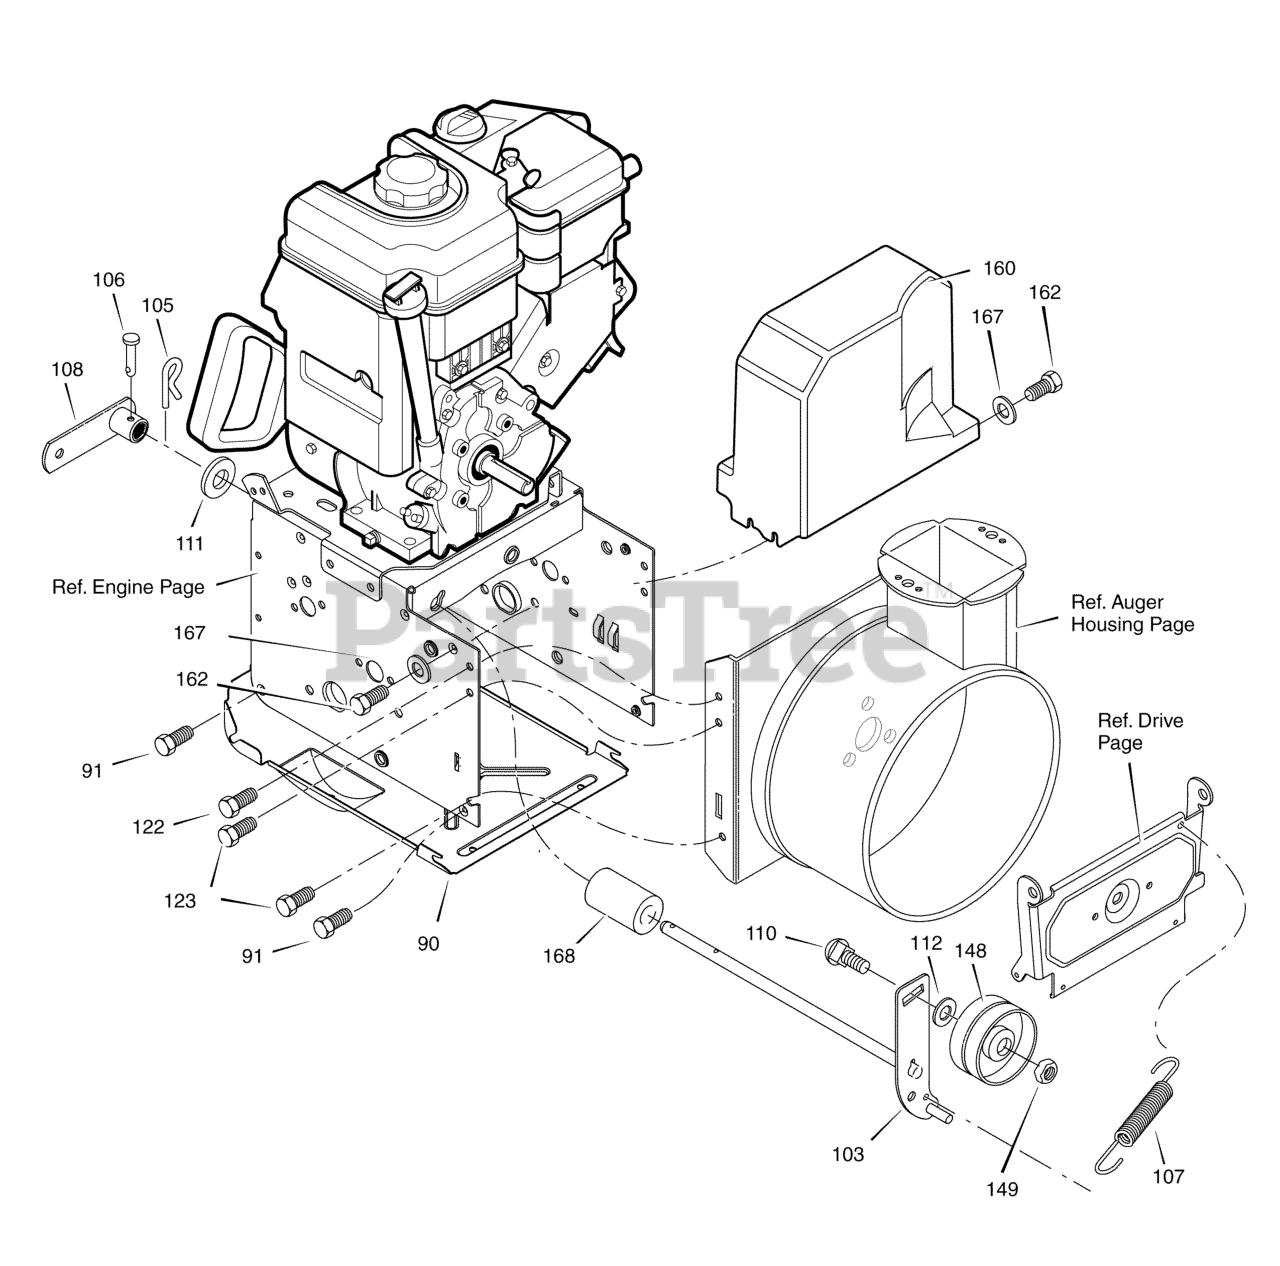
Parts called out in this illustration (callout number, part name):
90	COVER, BOTTOM
91	SCREW, 1/4-20 X .63
103	IDLER ASSEMBLY, AUGER
105	PIN, HAIR .38DIA X 1.64LG
106	PIN, CLEVIS 3/16" DIA
107	SPRING, TENSION
108	ARM CONTROL ASSEMBLY
110	BOLT, 3/8-16 X 1.25 CARRIAGE
122	SCREW, TAP 5/16-18 X .75
123	SCREW, TAP 5/16-18 X .50
148	PULLEY, IDLER
149	NUT, JAM 3/8-16
160	COVER, BELT
162	SCREW, TAP
167	WASHER, FLAT
168	SPACER, AUGER BRACKET
